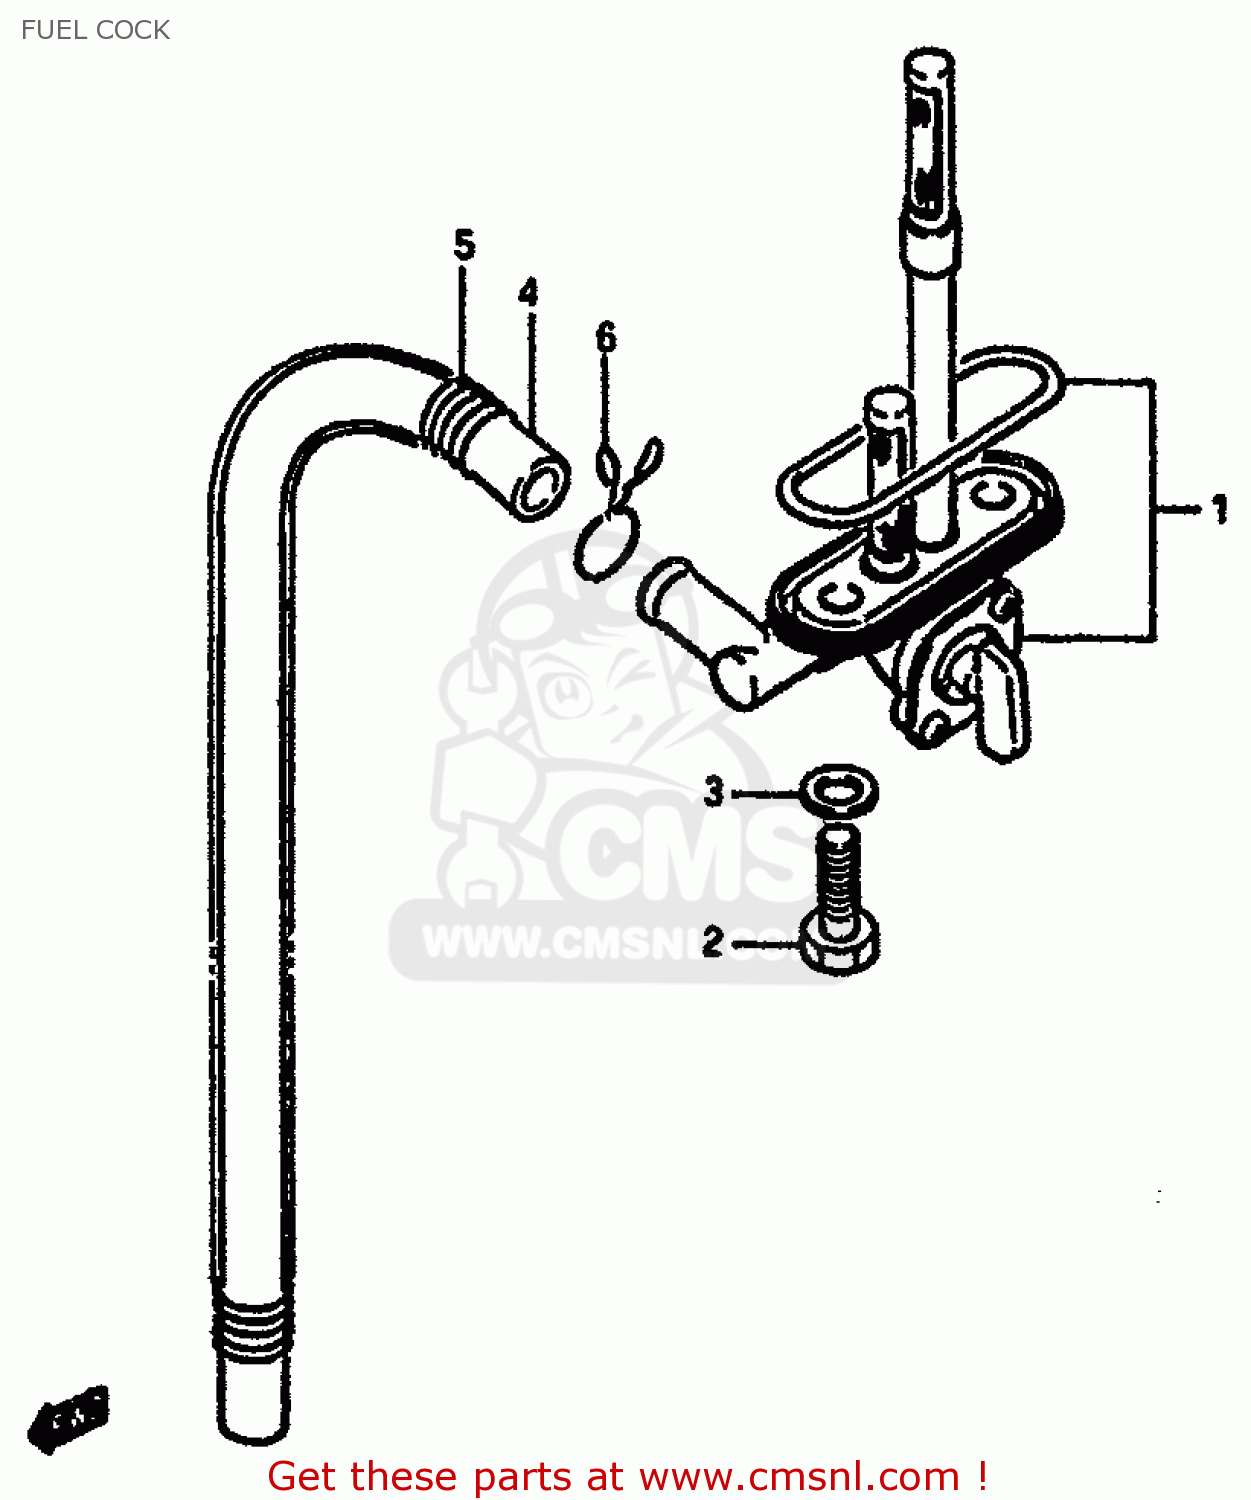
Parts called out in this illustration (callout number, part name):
1	COCK ASSY,FUEL
2	BOLT(6X20)
3	GASKET
4	HOSE
5	SPRING
6	CLIP
